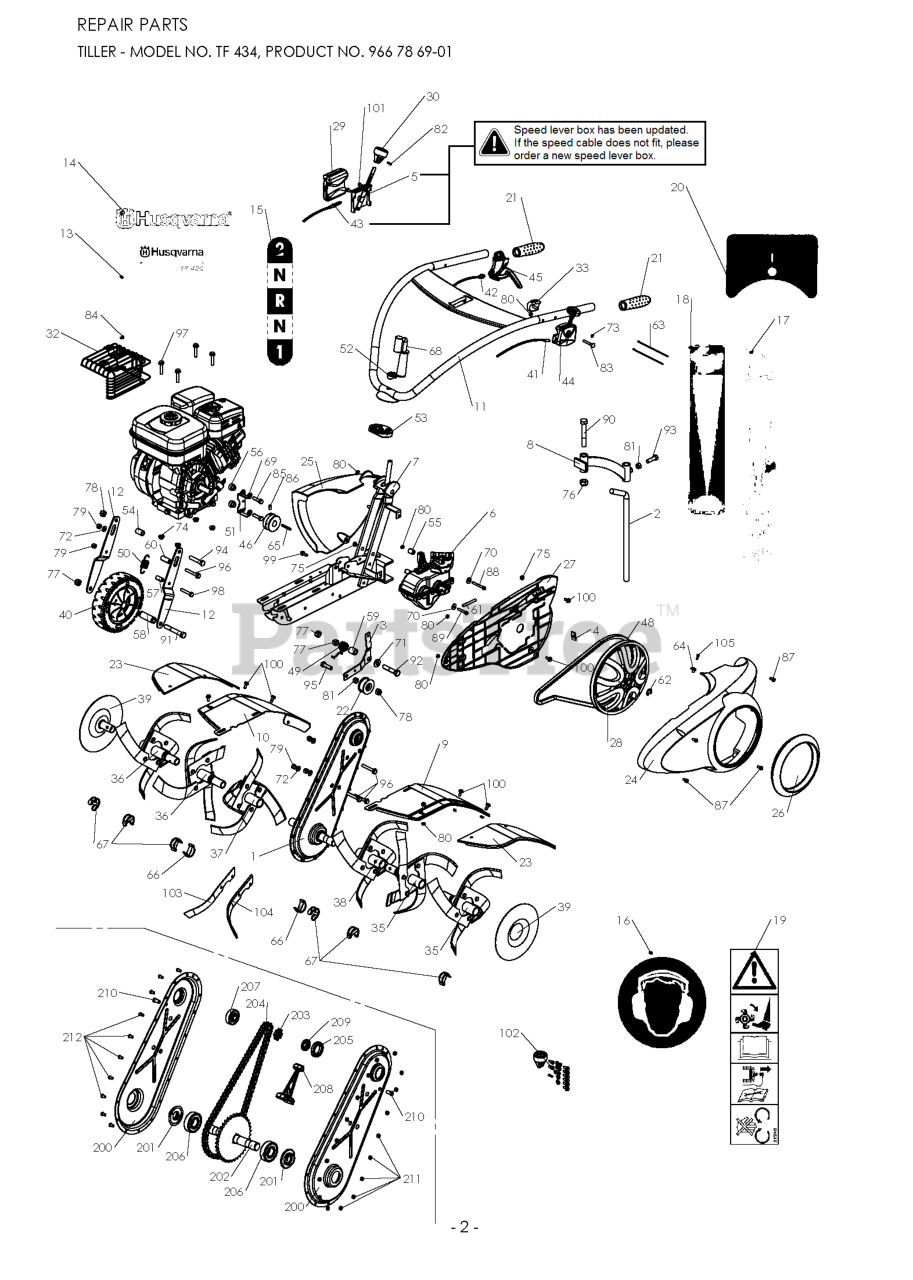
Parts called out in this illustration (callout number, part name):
41	THROTTLE CABLE
62	RETAINER RING
80	Blocking nut M 6 Z
205	BALL BEARING
211	Blocking nut M 6 Z
